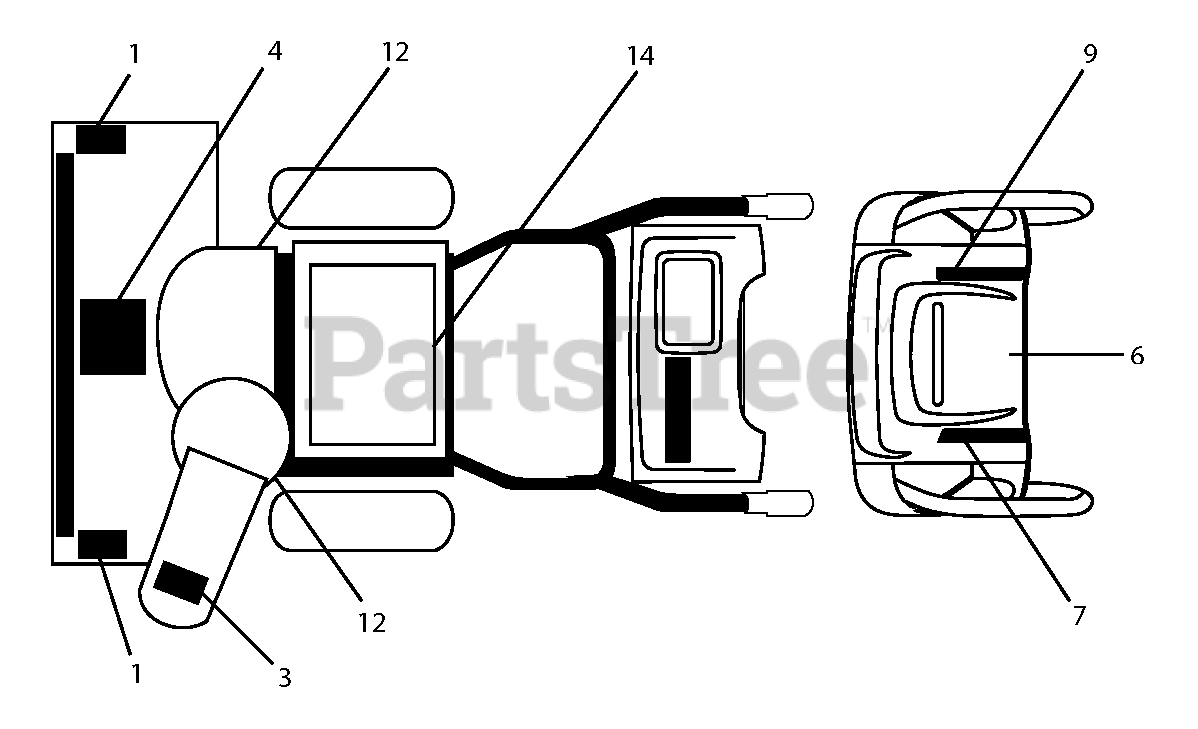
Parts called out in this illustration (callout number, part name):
1	DECAL.AUGER.SAFETY.
3	DECAL.CHUTE.SAFETY.
4	DECAL.AUGER."
7	DECAL.CONS.LT.WO/DEFL.GRY
9	DECAL.CONS.RT.SPD/LEV/PWRST.
12	DECAL.BELT.GUARD.
14	DECAL.FENDER
